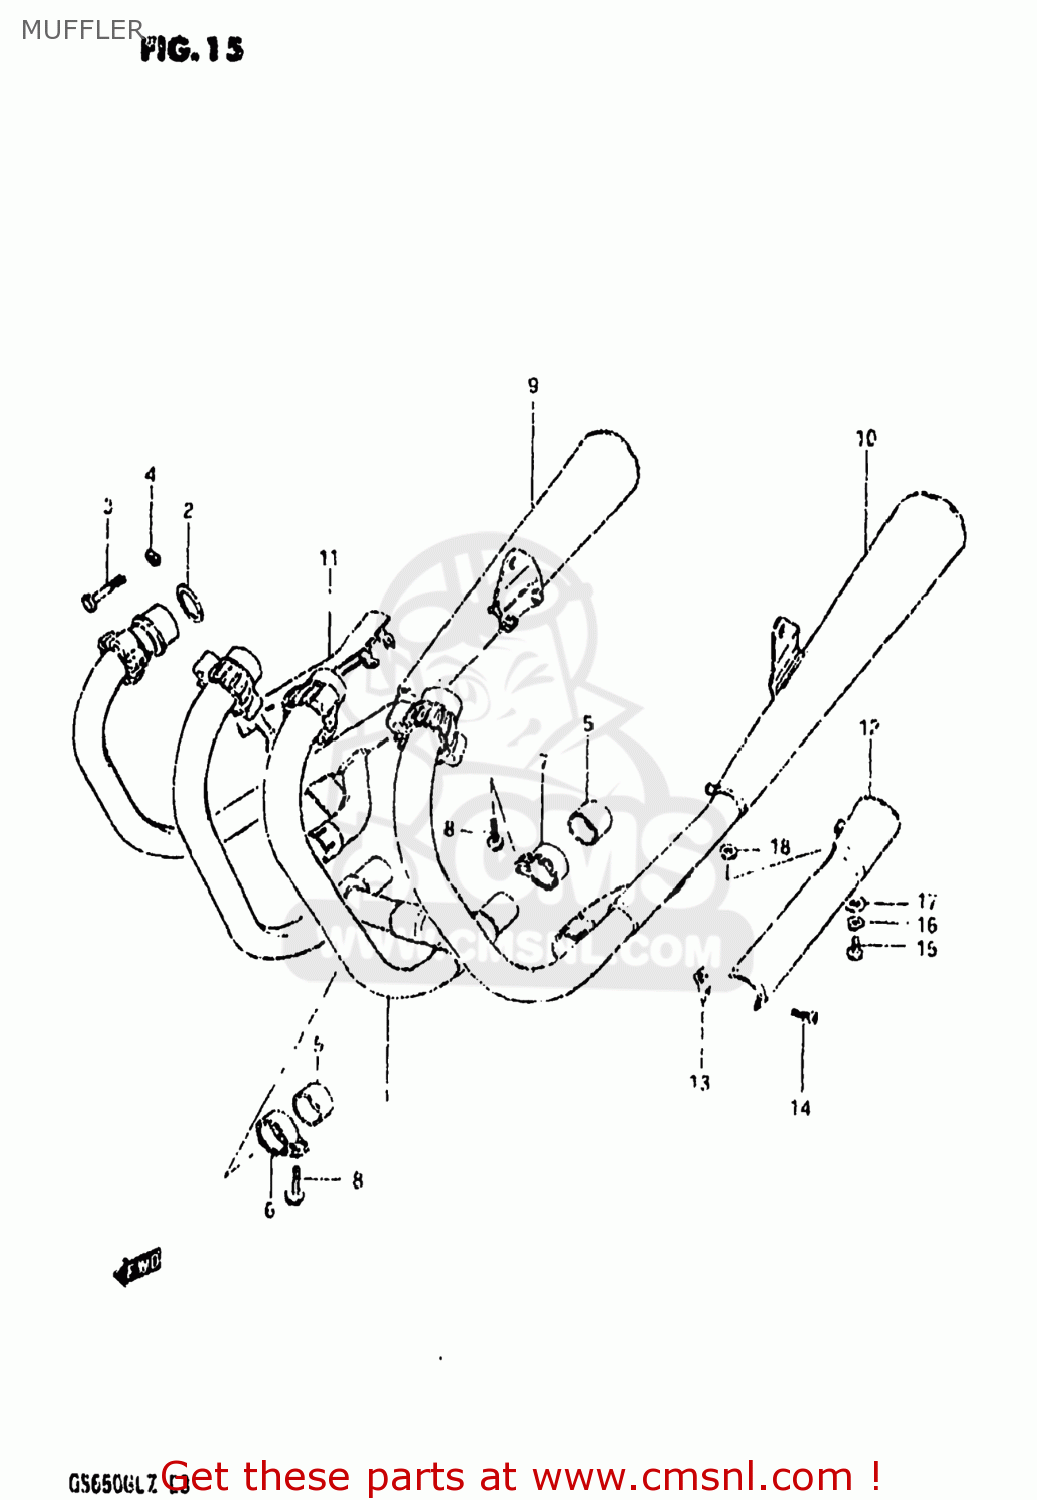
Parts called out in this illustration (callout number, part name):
1	PIPE,EXHAUST CTR
2	GASKET,EXHAUST PIPE (NAS)
3	BOLT 8X40
4	LOCK WASHER
5	CONNECTOR,MUFFLER
6	CLAMP,MUFFLER CONNECTOR,R
7	CLAMP,MUFFLER CONNECTOR,L
8	BOLT
9	MUFFLER ASSEMBLY
10	MUFFLER ASSEMBLY
11	COVER,MUFFLER,RIGHT
12	COVER,MUFFLER,LEFT
13	CLAMP,MUFFLER COVER
14	SCREW 5X20
15	SCREW 6X12
16	LOCK WASHER
17	WASHER, LOWER
18	GASKET 6.2X12X1.5 (MCA)
